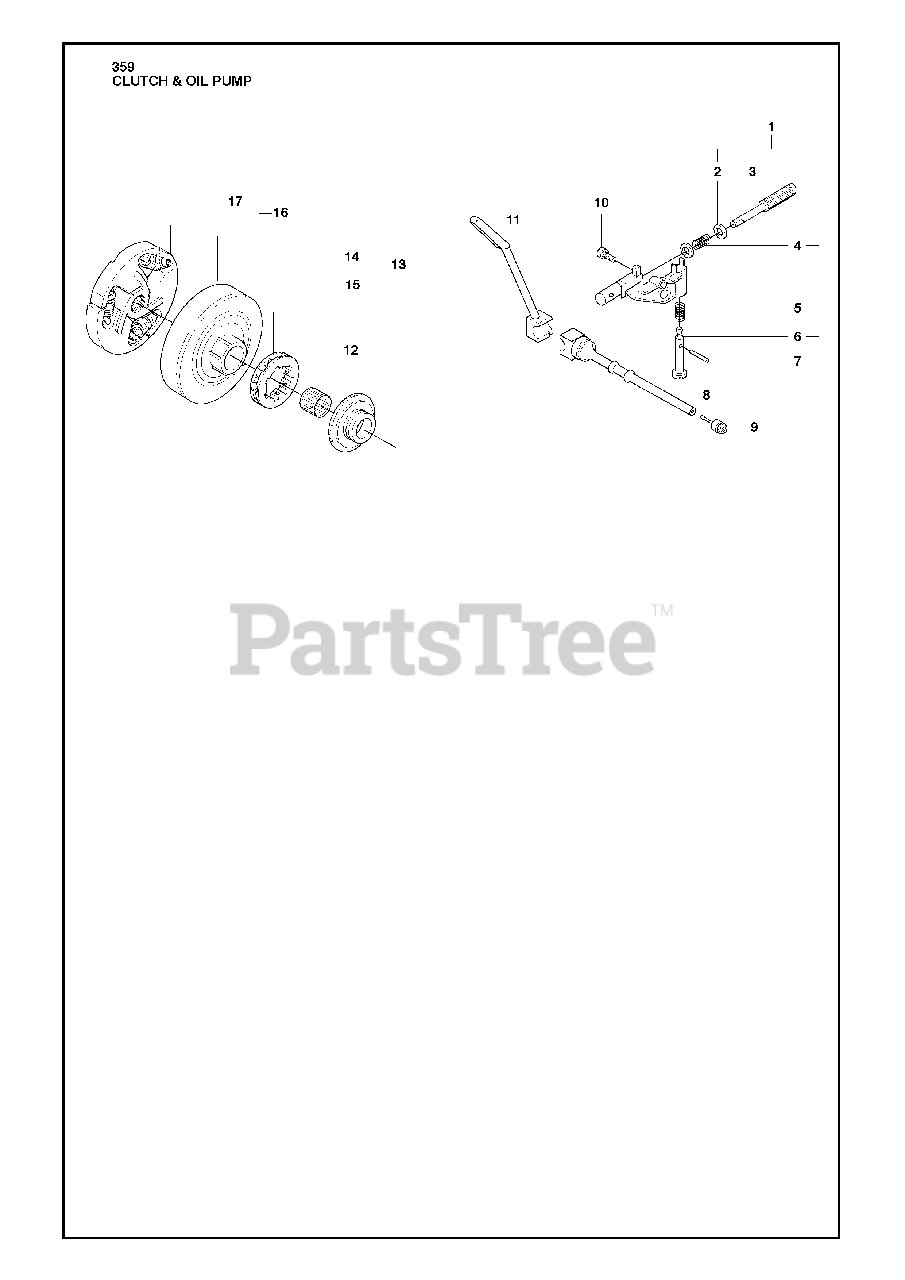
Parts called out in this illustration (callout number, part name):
1	OIL PUMP ASSY
3	PUMP PISTON
8	RP HOSE
9	OIL PLUMMET
12	PUMP GEAR
13	CLUTCH DRUM
14	RIM SPROCKET 7T .325
14	68210 RIMSPROCKET
15	NEEDLE BEARING
16	CLUTCH
